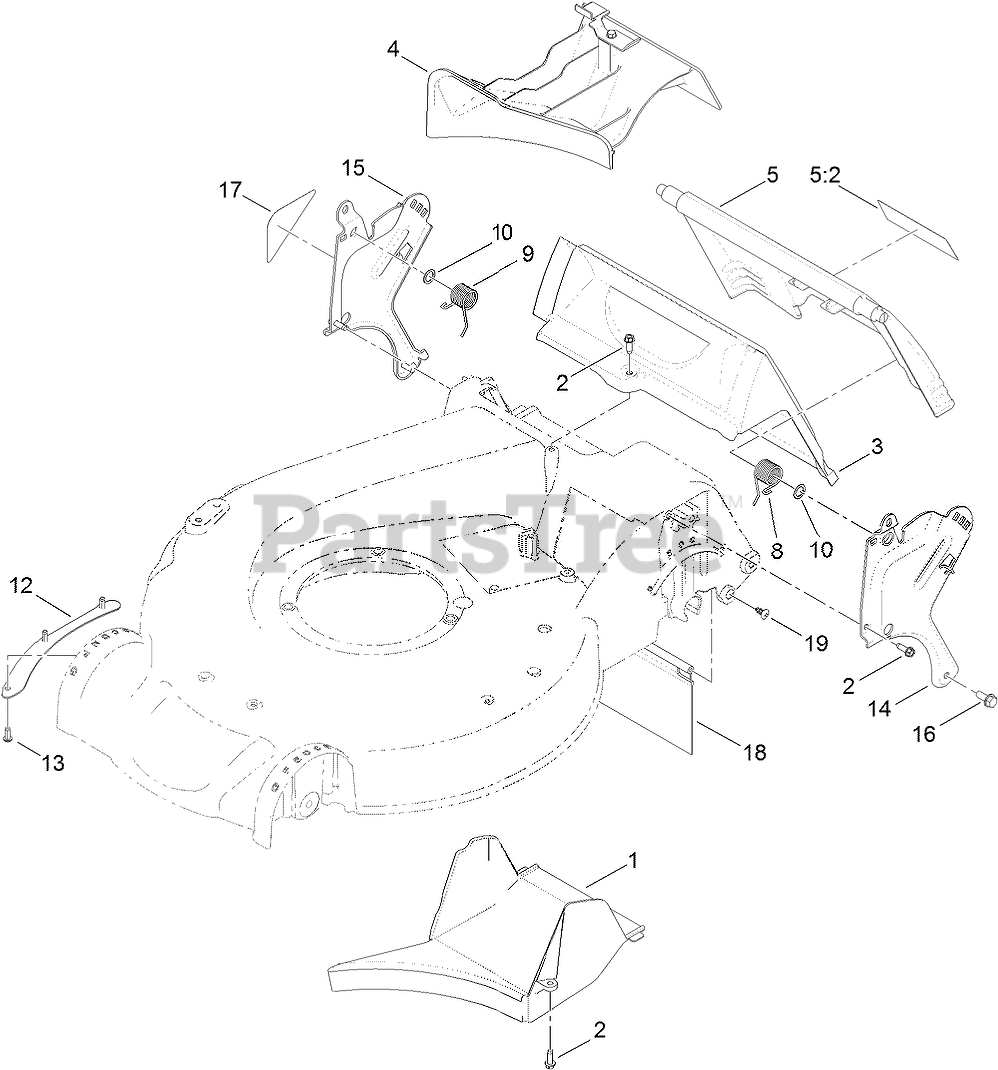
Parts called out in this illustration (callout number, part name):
1	TUNNEL-DISCHARGE
2	SCREW-HWHTF
4	MULCH PLUG ASM
5	REAR DOOR ASM
5:2	DECAL-WARNING
8	SPRING-TORSION
9	SPRING-TORSION
10	WASHER-NYLON
12	SHEET-LIP
13	SCREW
14	BRACKET-HANDLE, LH
15	BRACKET-HANDLE, RH
16	SCREW-HWHTF
17	DECAL-INSTRUCTION
18	SHIELD-TRAILING
19	SCREW-PTH
